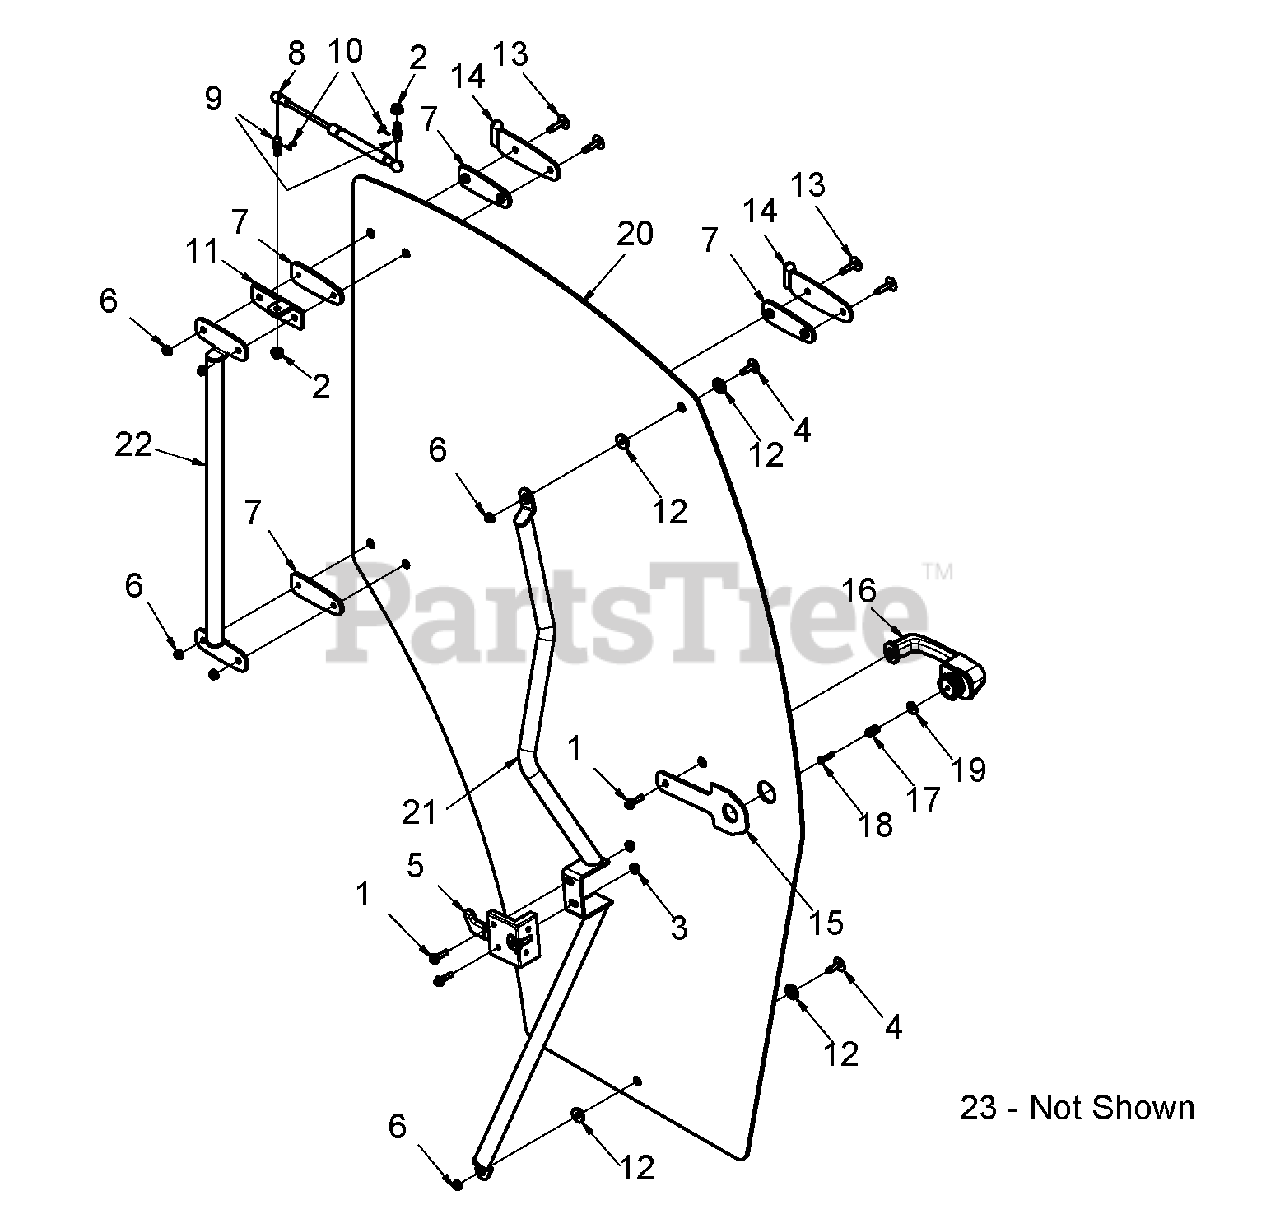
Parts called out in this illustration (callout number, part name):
1	Bolt, Hex M6-1.0 x 25
2	Nut, .31-18 Nyloc Flange
3	Flange Nut, M6 x 1.0
4	Bolt, Step 1/4 x 1 Black
5	Latch, Left Door
6	Nut, Flange 1/4 Black
7	Neoprene, Injection Mold, 5MM, Black
8	Shock, Gas
9	Stud, Gas Shock Ball
10	Clip, Gas Shock
11	Plate, LH Gas Shock Mount
12	Bushing, 5MM Black Neoprene
13	Bolt, Step 1/4 X 1 1/2 Black
14	Weldment, Door Hinge (Left Door)
15	Bushing, Door Handle
16	Handle, Door Push-Button
17	Nut, Coupler 10-32X1 1/4
18	Screw, Machine 10-32X1 1/4
19	Washer, Flat - 3/16
20	Glass, Cab Door
21	Weldment, Door Latch Support (Left Door)
22	Weldment, Door Hinge Support
23	.2’ Weather Strip, Door Glass
